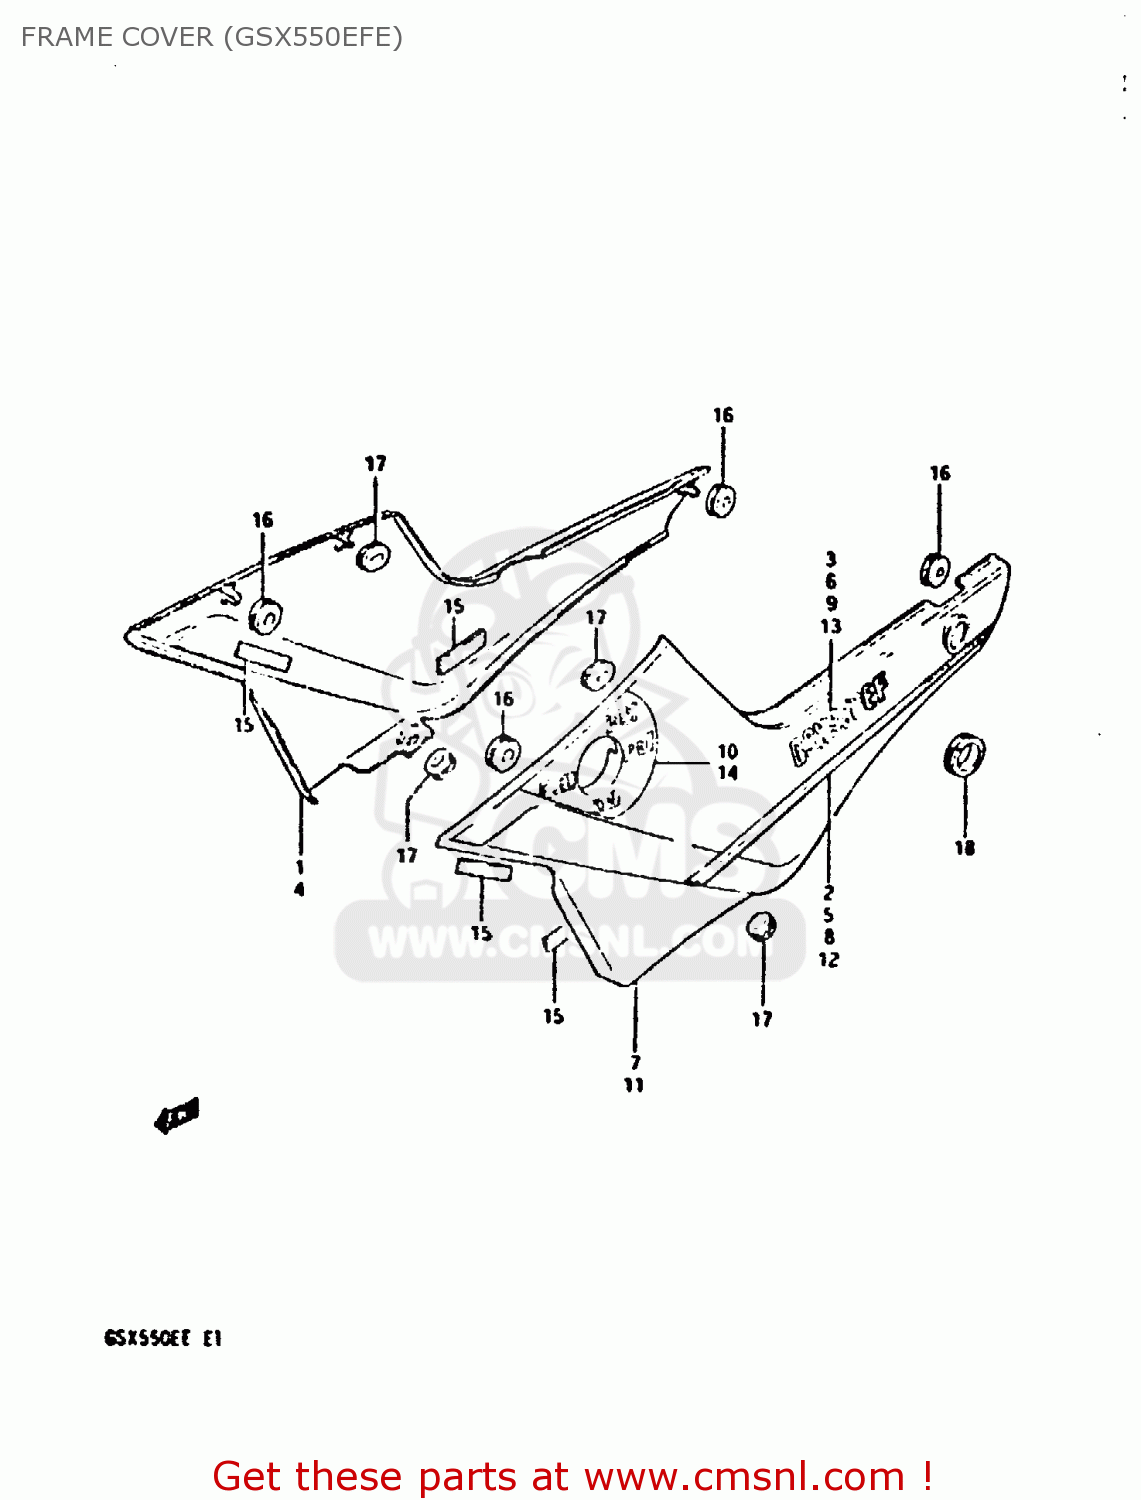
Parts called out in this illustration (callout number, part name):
1	COVER SET, FRAME RH
2	TAPE SET,FRAME COVER,RIGHT
3	EMBLEM
4	COVER SET, FRAME RH
5	TAPE SET, FRAME COVER RH
6	EMBLEM
7	COVER SET, FRAME LH
8	TAPE SET,FRAME COVER
9	EMBLEM
10	EMBLEM,FUEL COCK
11	COVER SET, FRAME LH
12	TAPE SET, FRAME COVER LH
13	EMBLEM
14	EMBLEM,FUEL COCK
15	RUBBER,FRAME COVER
16	CUSHION
17	CUSHION
18	GROMMET,SEAT LOCK HOLE
